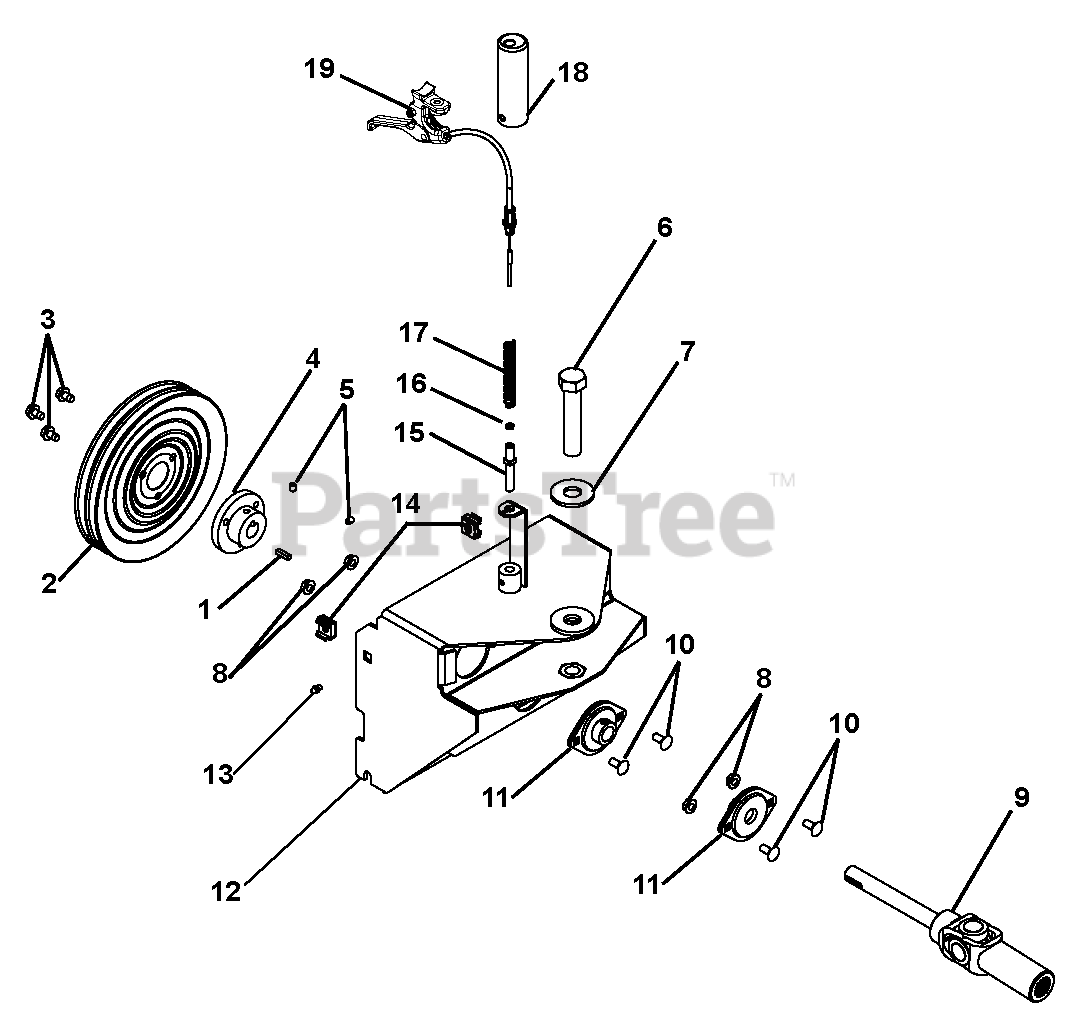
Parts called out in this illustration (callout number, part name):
1	Key-Square .188 x .75 x .188
2	Pulley, Spin Form Dual Groove
3	Screw-Tapping .31-18 x .50 Hex Washer Head Thread Rolling
4	Hub, Pulley
5	Screw-Set .25-20 x .38 Socket Head Cup Point Nylon Oil Hardene
6	HHCS .75-16 UNF x 3.75
7	Washer-Flat-Steel .812 x 2.00 x .148
8	Nut-Locking-Top-Flange .31-18
9	Driveline, Series
10	Bolt-Round Head Square Neck .31-18 x .75
11	Bearing, 3/4" Flangette
12	Mounting Frame
13	Fitting-Lube .25-28 x .256
14	Nut-Retainer .38-16
15	Pin, Swing MCD-Trigger Release
16	Nut-Hex 10-24
17	Spring, Compression .51" x 3.5"
18	Cap, Vinyl
19	Cable, Control Swing-MCD
